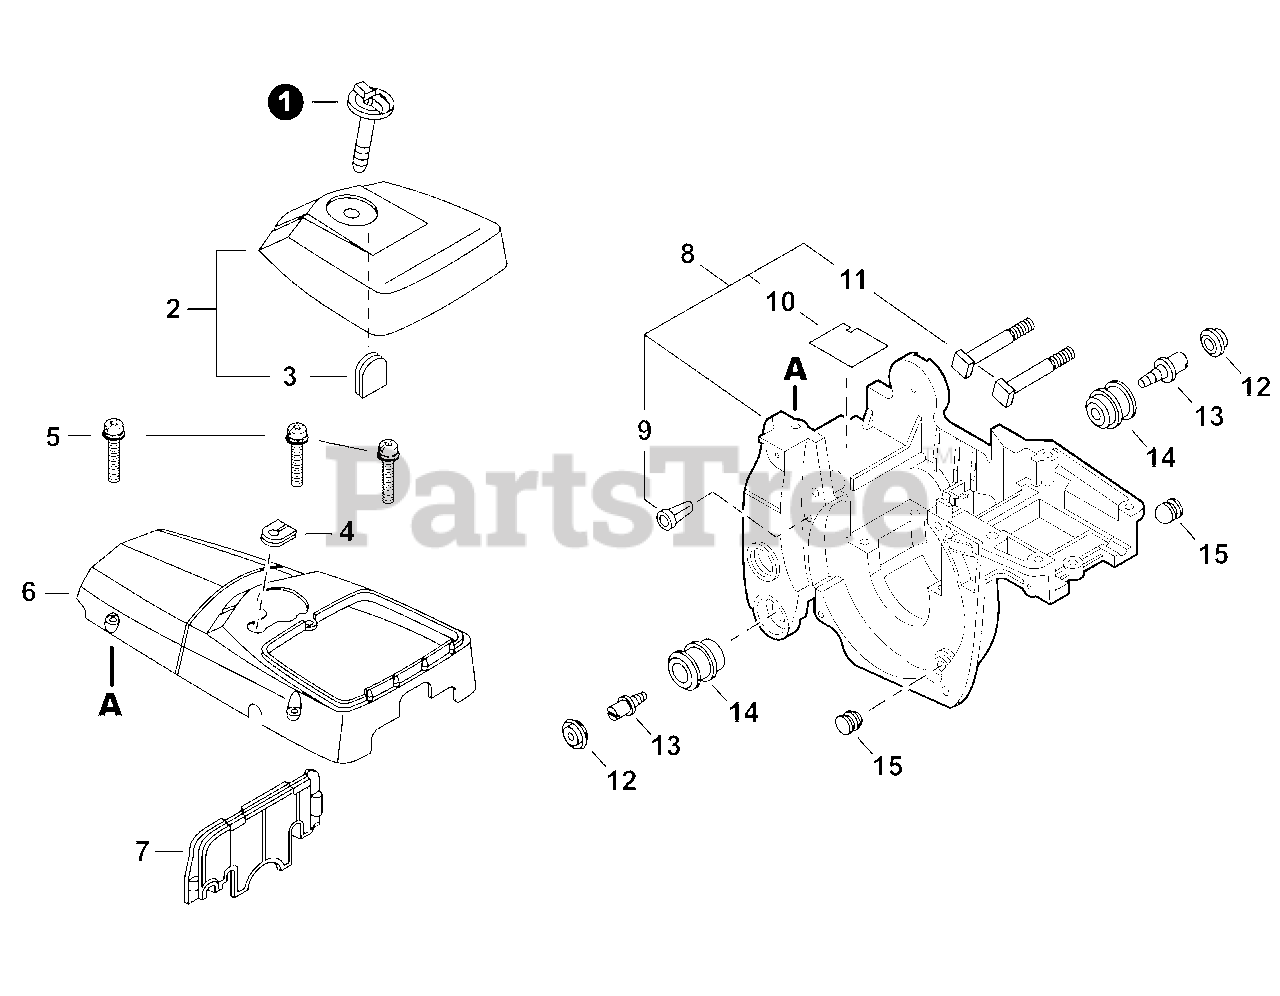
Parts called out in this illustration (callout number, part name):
1	THUMBSCREW
2	COVER ASSY, AIR FILTER
4	GROMMET, HT
5	SCREW 5×20
6	COVER, ENGINE
7	PLATE, INSULATOR
8	COVER ASSY, ENGINE
9	VENT ASSY
10	SHIELD, HEAT
11	STUD, GUIDE BAR 8
12	CAP, CUSHION
14	CUSHION 5
15	CUSHION
